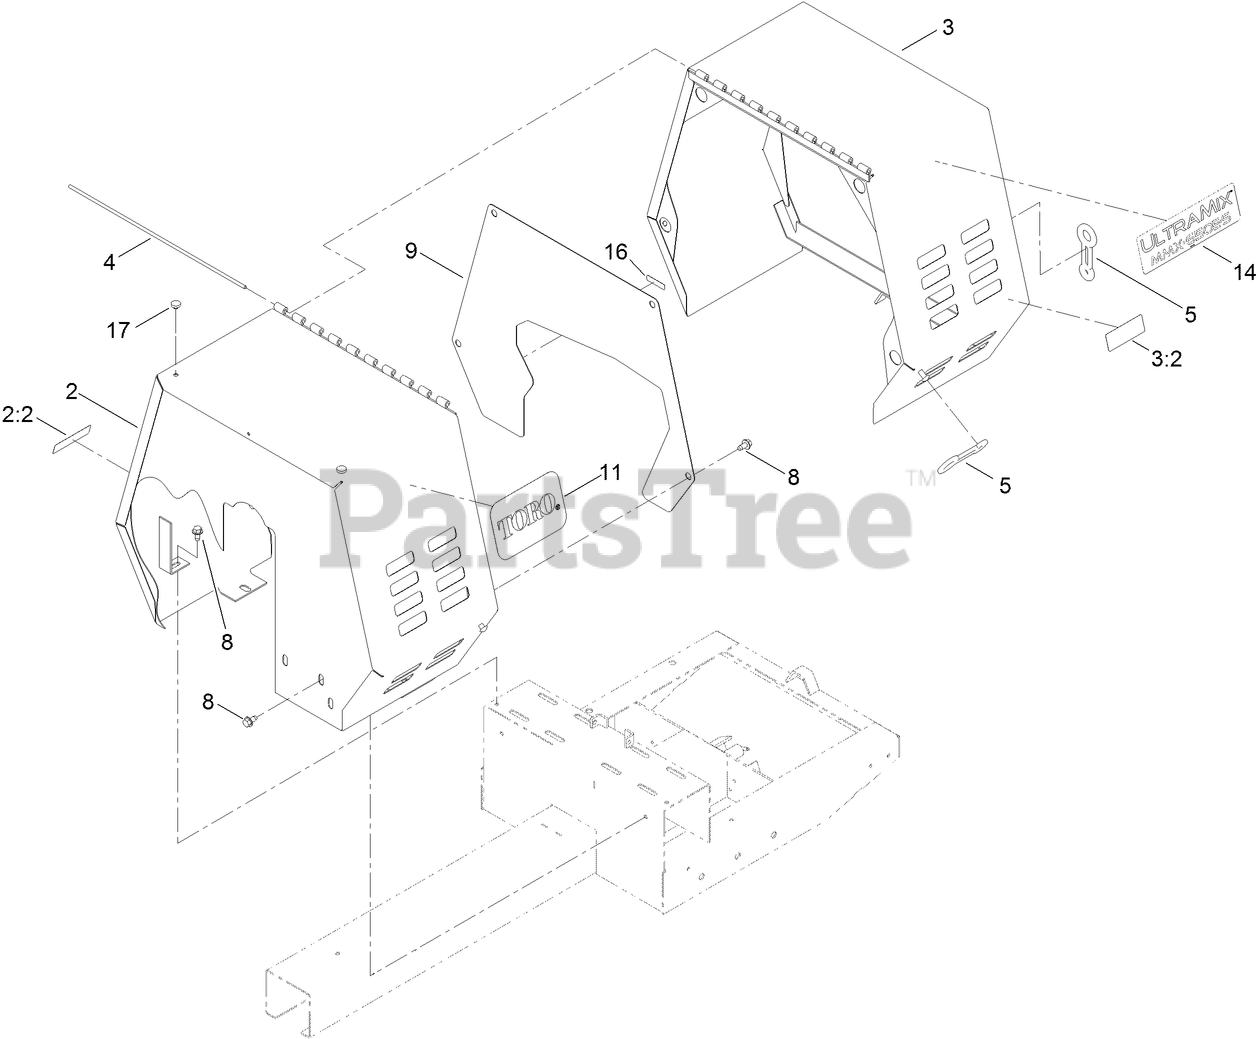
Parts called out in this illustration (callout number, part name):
2	STATIONARY COWL ASM
2:2	DECAL-ARRESTOR, SPARK
3	MOVABLE COWL ASM
3:2	DECAL-WARNING
5	LATCH-RUBBER
8	SCREW-HWH
9	PLATE-GUARD
11	DECAL
16	DECAL-GREASE
17	BUMPER
